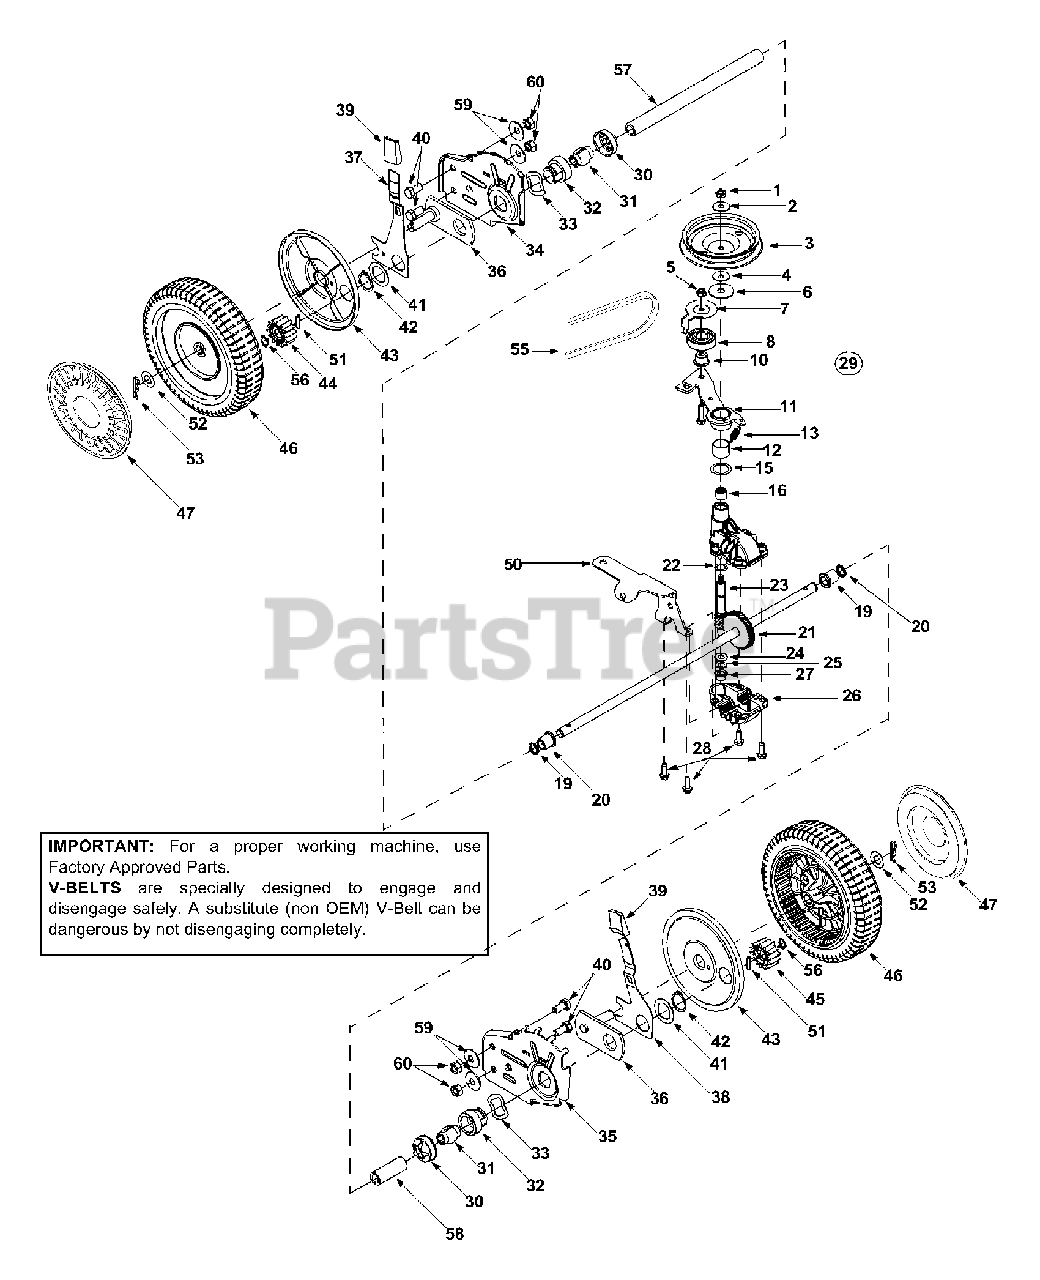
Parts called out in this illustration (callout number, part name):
1	Hex Jam Nut 5/16-24
2	Bell Washer .325 x .930 x .045
3	Pulley, 3.82 x .313 x .68
4	Bell Washer .325 x .930 x .045
5	Lock Nut 1/4-28
6	Flat Washer .442 x 1.38 x .060
7	Belt Keeper
8	Ball Bearing
10	Flange Spacer
11	Idler Bracket Assembly
12	Bearing Sleeve
13	Flat Washer .504 x .700 x.030
15	Flat Washer .865 x 1.145 x .030
16	Needle Bearing .438 x .625 x .500
19	Oil Seal .500 x .687 x .094
20	Flange Bearing
21	Output Shaft
22	Flat Washer .504 x .700 x .030
23	Pinion Shaft 10T
24	Thrust Washer .375 x .70 x .030
25	Thrust Washer .388 x .625 x .062
26	Lower Housing
27	Flange Bearing .378 x .531 x .370
28	Hex Screw w/Washer 1/4-20 x .750
29	Transmission Assembly Comp.
30	Bearing Retainer
31	Bearing Sleeve .50 I.D.
32	Bearing Support
33	Wave Washer 1.5 x 1.0 x .029
37	RH Front Lever
38	LH Front Lever
39	Knob
40	Hex Cap Screw 3/8-16 x .75
41	Washer DD 1.5" O.D.
42	Snap Ring 1.0 dia.
43	Wheel Dust Cap
44	Gear 14T R.H.
45	Gear 14T L.H.
46	Wheel, 8x2 x 1.75
47	Hubcap: Yellow
50	Cable Idler Bracket
51	Dowel Pin
52	Flat Washer 1/2 x 1.00 x .063
53	Cotter Pin .08 x 1.42
55	Belt
56	Snap Ring
57	Slev. Spacer
58	Slev. Spacer
59	Bell Washer
60	Hex Nut 3/8-16
